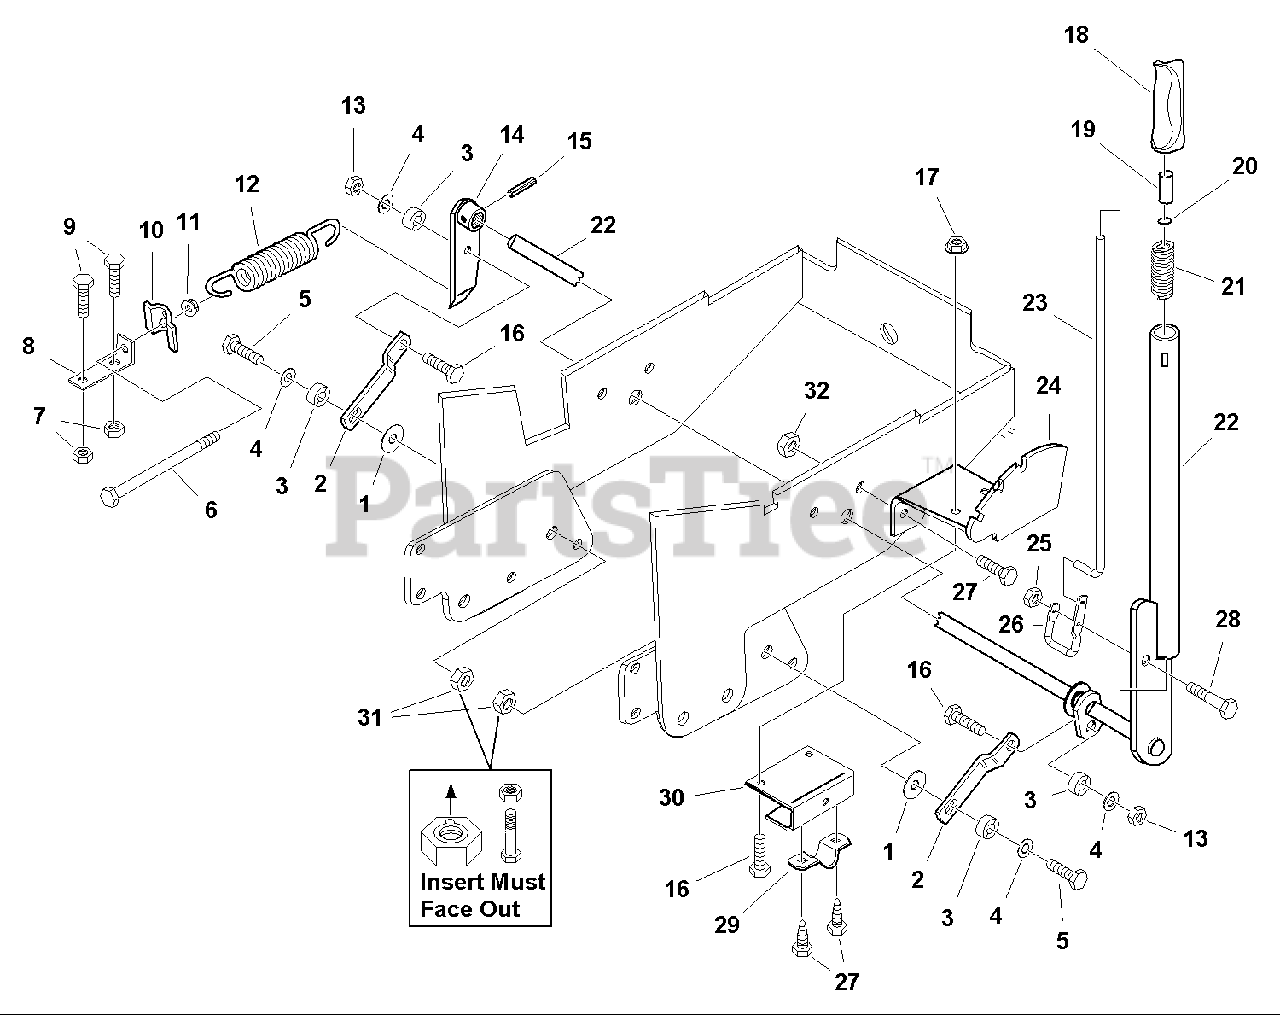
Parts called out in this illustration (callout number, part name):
1	WASHER, 3/8, Black
4	WASHER,3/8, Black
5	CAPSCREW, Hex Head, 3/8-16 x 1-3/4, Black
6	CAPSCREW, Hex Washer Head, 5/16-18 x 4-1/2, Black
7	NUT, Hex, 5/16-18, Black
8	ANCHOR, Spring
9	CAPSCREW, Hex Head, 5/16-18 x 2-1/2
10	RETAINER, Spring
11	NUT, Speed, 5/16-18
12	SPRING, Extension, 9" Long
13	NUT, Hex Flange Lock, 3/8-16, Black
14	BAR & HUB ASSEMBLY
15	PIN, Spring, 5/16 x 1-1/2
16	CAPSCREW, Hex Head, 3/8-16 x 1-1/4, Black
17	NUT, Hex Flange Whiz Lock, 5/16-18, Black
18	GRIP, Lift Lever
19	BUTTON, Red
20	NUT, Push, 1/4, Black
21	SPRING, Compression, 3.85" Long
22	HANDLE ASSEMBLY, Lift
24	QUADRANT, Lift
25	NUT, Hex Lock ESNA, 1/4-20, Black
26	LATCH "U" Wire
27	CAPSCREW, Hex Head, Whiz Lock, 5/16-18 x 3/4, Black
28	CAPSCREW, Hex Head, 1/4-20 x 2-1/4, Black
29	STRAP
30	BRACE, Support
31	NUT, Hex Lock Aluminum Insert, 3/8-16
32	NUT, Hex Whiz Lock , 3/8-16
